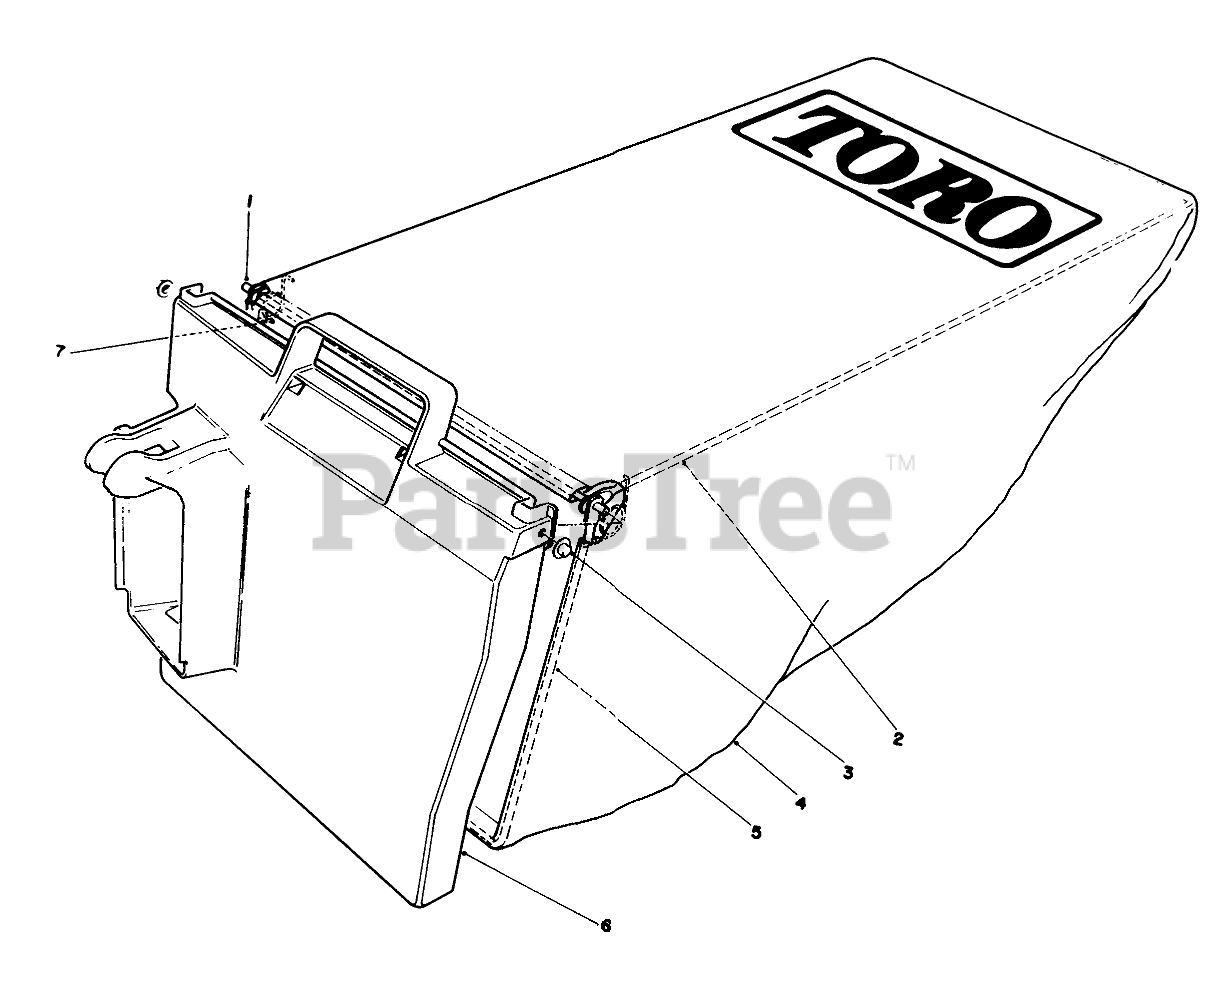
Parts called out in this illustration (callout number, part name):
1	HINGE PIN
2	BAG FRAME
3	NUT-PUSH
5	BAG FRAME
6	Door-Bag
7	SPRING
